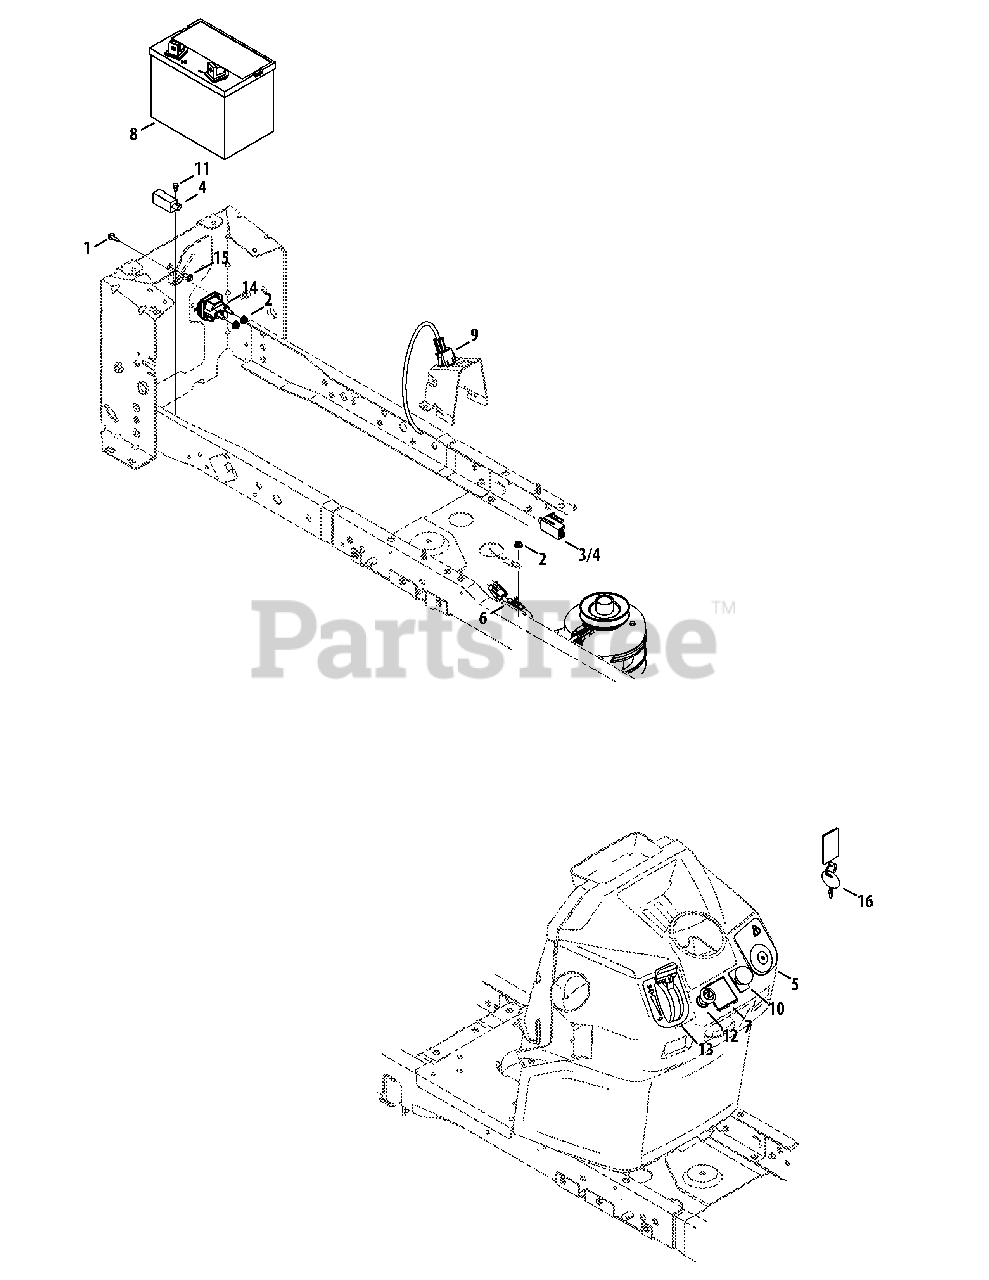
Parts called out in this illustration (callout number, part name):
1	Screw, M6-1 x .625
2	Nut, Jam Lock, 1/4-20, Nylon
3	Switch, 3-Pole (Man. PTO)
4	Switch, Interlock
5	Key Switch (Man. PTO)
6	Jumper Harness (Elec. PTO)
7	Hour Meter
9	Dash Harness (Man. PTO)
10	Dash Plug (Man. PTO)
11	Shoulder Screw, #10-32 x .500
12	Choke Plug
13	Throt/Choke Cable, 38"
14	Solenoid
15	Self-tapping Screw, 1/4-20 x .625
16	Key, Assembly
